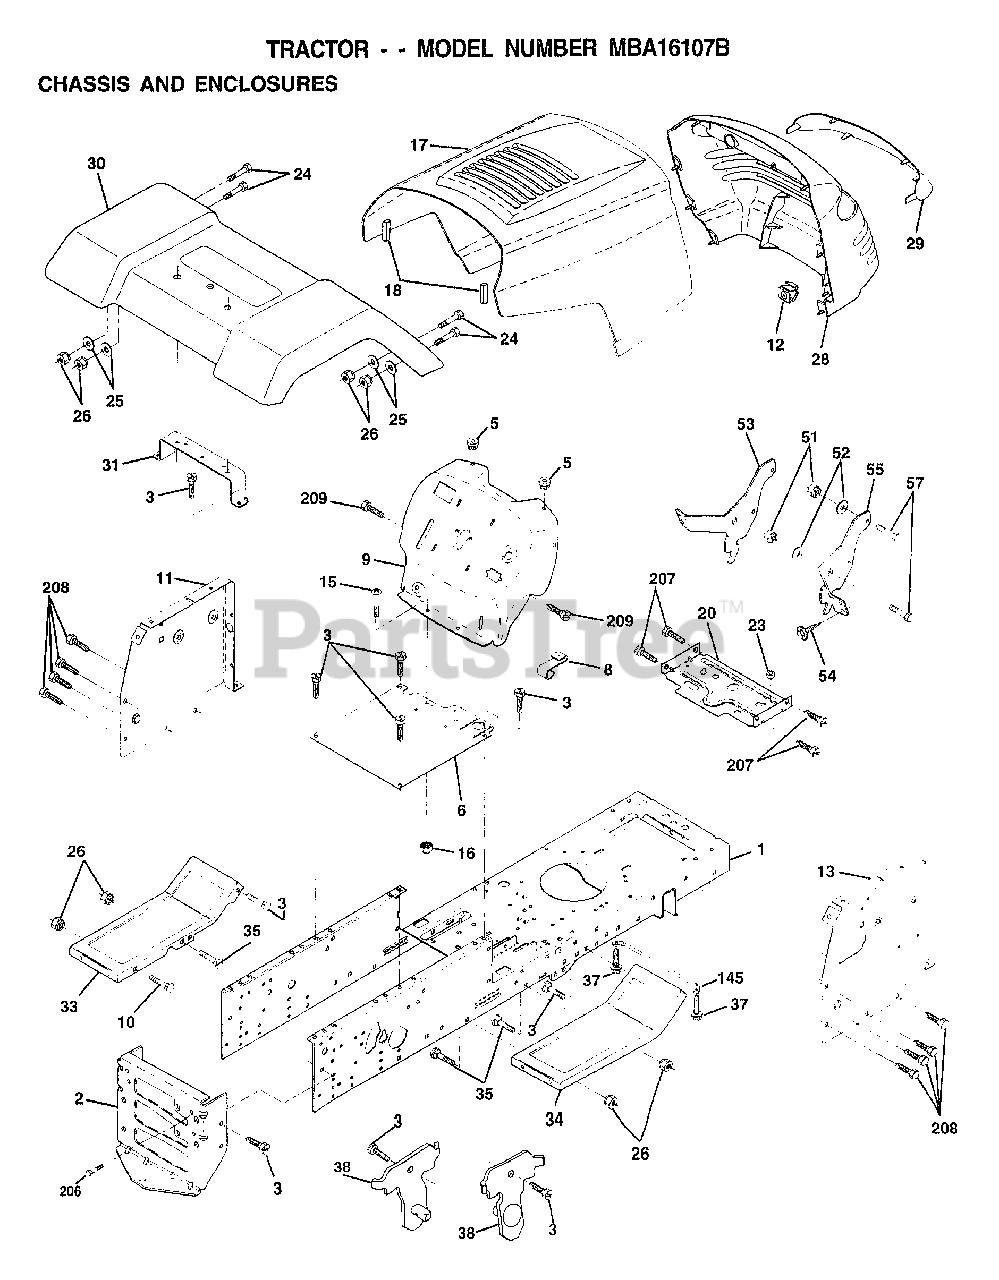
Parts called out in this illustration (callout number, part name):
2	DRAWBAR
3	SCREW
5	BUMPER-HOOD/DASH
6	SADDLE
8	CLIP.RETAINER
9	DASH
11	"PANEL-DASH,LH"
12	CLIP.TINNERMAN
15	SCREW
17	HOOD.PNT.W/TRIM
20	"PLATE-MTG,BATT/FU"
24	BOLT
25	WASHER
26	NUT
28	GRILLE
29	LENS.GRILLE
30	FENDER PNT
31	BRKT FENDER
33	FOOTREST.LH.YT/GT
34	FOOTREST.RH.LT/YT
35	BOLT
37	SCREW LT
38	BRKT ASM PIVOT MOWER REAR
51	NUT
52	WASHER
53	BRACKET.GRILLE.LH
54	SCREW.HEX.WS.HD
55	BRACKET.GRILLE.RH
145	"ROD POVOT,CHASSIS"
206	BOLT SHOULDER
207	SCREW
208	SCREW
209	SCREW
